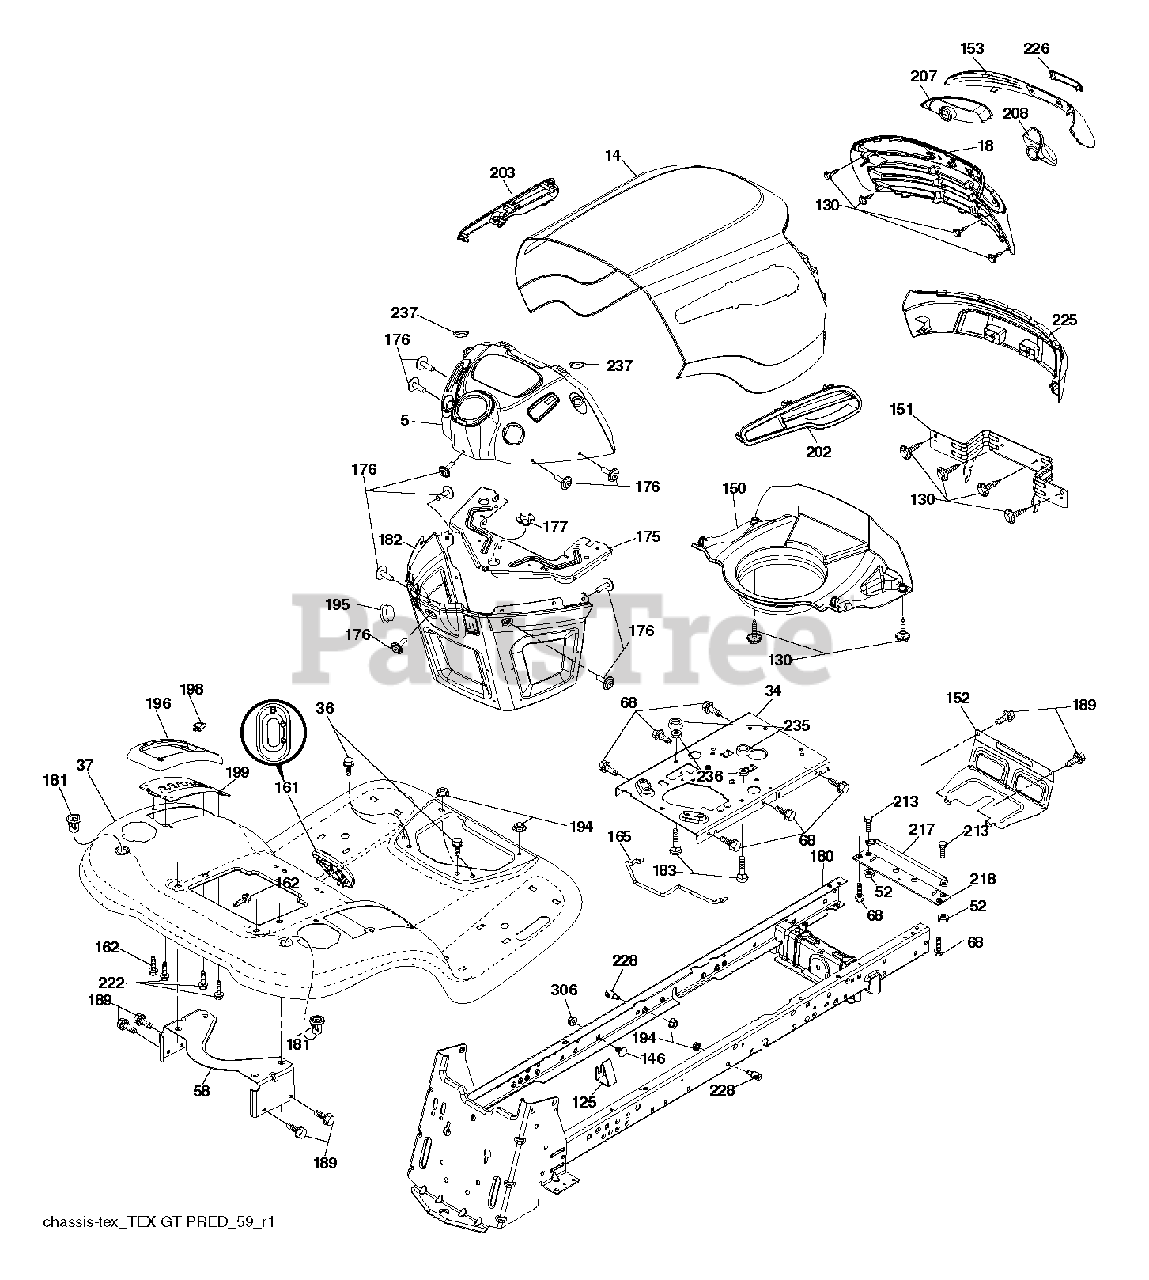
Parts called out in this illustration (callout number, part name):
14	HOOD.PNT.PREDATOR.YT/GT.BLACK
18	GRILLE.SVC.PREDATOR.YT.TEX
34	PLATE.ENGINE.WELDED.CHASSIS
36	SCREW 5/16"
52	LOCKNUT
58	BRKT.SUPPORT.FNDR/TANK
68	SCREW LT
125	CLIP.FUEL.LINE
130	SCREW.#10 X 0.750.BOS (2 2)
146	BOLT.RDHD.SHT.SQNK.3/8-16X5/8
150	PREDATOR.YT.GT.HOOD.AIR DUCT
151	BRACKET.PIVOT.PREDATOR
152	SHIELD.BROWNING.W/TEX
153	LENS.BAR.PREDATOR.YT.CLEAR
161	CONSOLE.FUEL.WINDOW.STGT.BLACK
162	SCREW.HI-LO.CONSOLE
165	SUPPORT.TANK.REAR.W/TEX
175	PLATE.CROSSMEMBER.HUSQ
176	SCREW.#10-24X5/8.RN.QU
177	BUSHING,STEERING
180	CHASSIS.GT.SLOPED.DRAWBAR.
181	FEND/FTRST.PCH.CPH.NFW
182	DASH LOWER.HUSQ.PRED NO CRUISE
183	BOLT.5/16-18X1-1/4 FULL THD
189	SCREW
194	NUT LOCK HEX FLANGE 5/16-18
195	PLUG.HOLE.DASH.
198	INDICATOR.DECK.LIFT.RED
199	PLATE DECK LIFT
202	VENT.SIDE.HOOD.RH.PREDATOR.BLK
203	VENT.SIDE.HOOD.LH.PREDATOR.BLK
213	BOLT
217	ROD.PIVOT.HOOD
218	X-PIECE.HOOD.STOP.NON/
222	SCREW.1/4-20X5/8
228	STUD.FASTNER.W/ANTI-ROTATE
235	SPACER FENDER
236	NUT.CENTERLOCK.5/16-
237	PLUG.MOUNT.CARGO.BLK
306	NUT LOCK FLG 3/8-16 UNC
